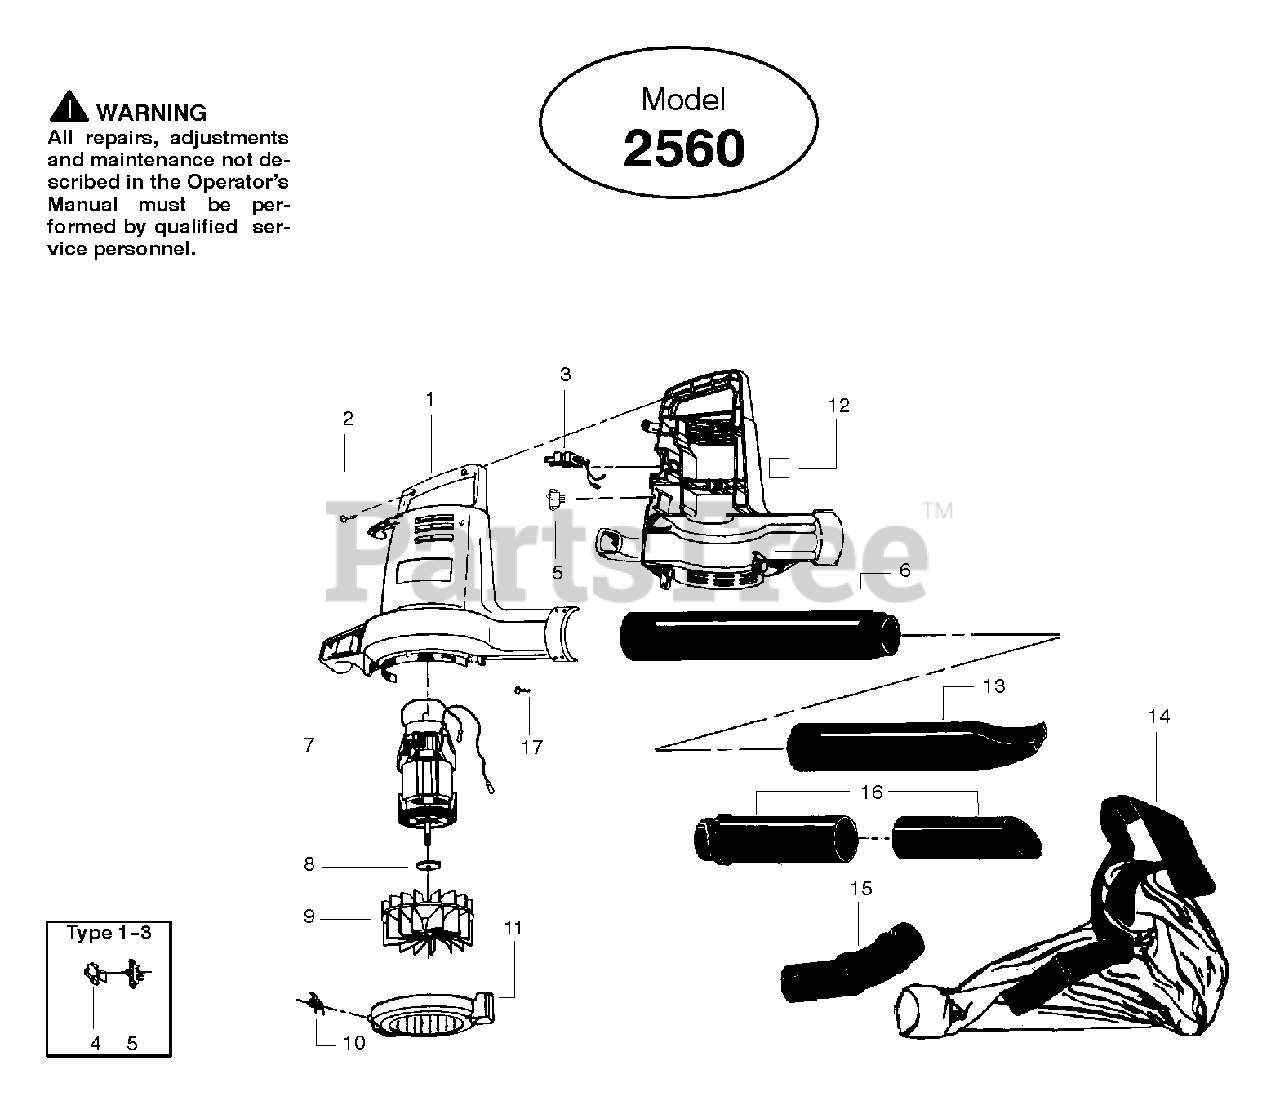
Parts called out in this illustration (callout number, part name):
1	Housing Set Type 1
1	Housing Set Type 2
1	Housing Set Type 3
1	Housing Set Type 4
3	Wire Harness Type 1 & 2
3	Wire Harness Type 3
3	Wire Harness Type 4
4	Switch Cover (Type 1-3)
5	Switch Type 1 & 2
5	Switch Type 3
5	Switch Type 4
6	Blower Tube Type 1
6	Blower Tube Type 2,3,4
7	Motor Ass'y. Type 1 & 2
7	Motor Ass'y. Type 3,4
9	Impeller Type 1 & 2
9	Impeller Type 3,4
11	Assy-Cover Spring
12	Pad (Type 1 & 2)
13	Nozzle Type 1
13	Nozzle Type 2,3,4
14	Vacuum Bag Kit Type 1
14	Vacuum Bag Kit Type 2,3,4
15	Elbow (Type 1 only)
16	Vacuum Tube Kit Type 1
16	Vacuum Tube Kit Type 2,3,4
